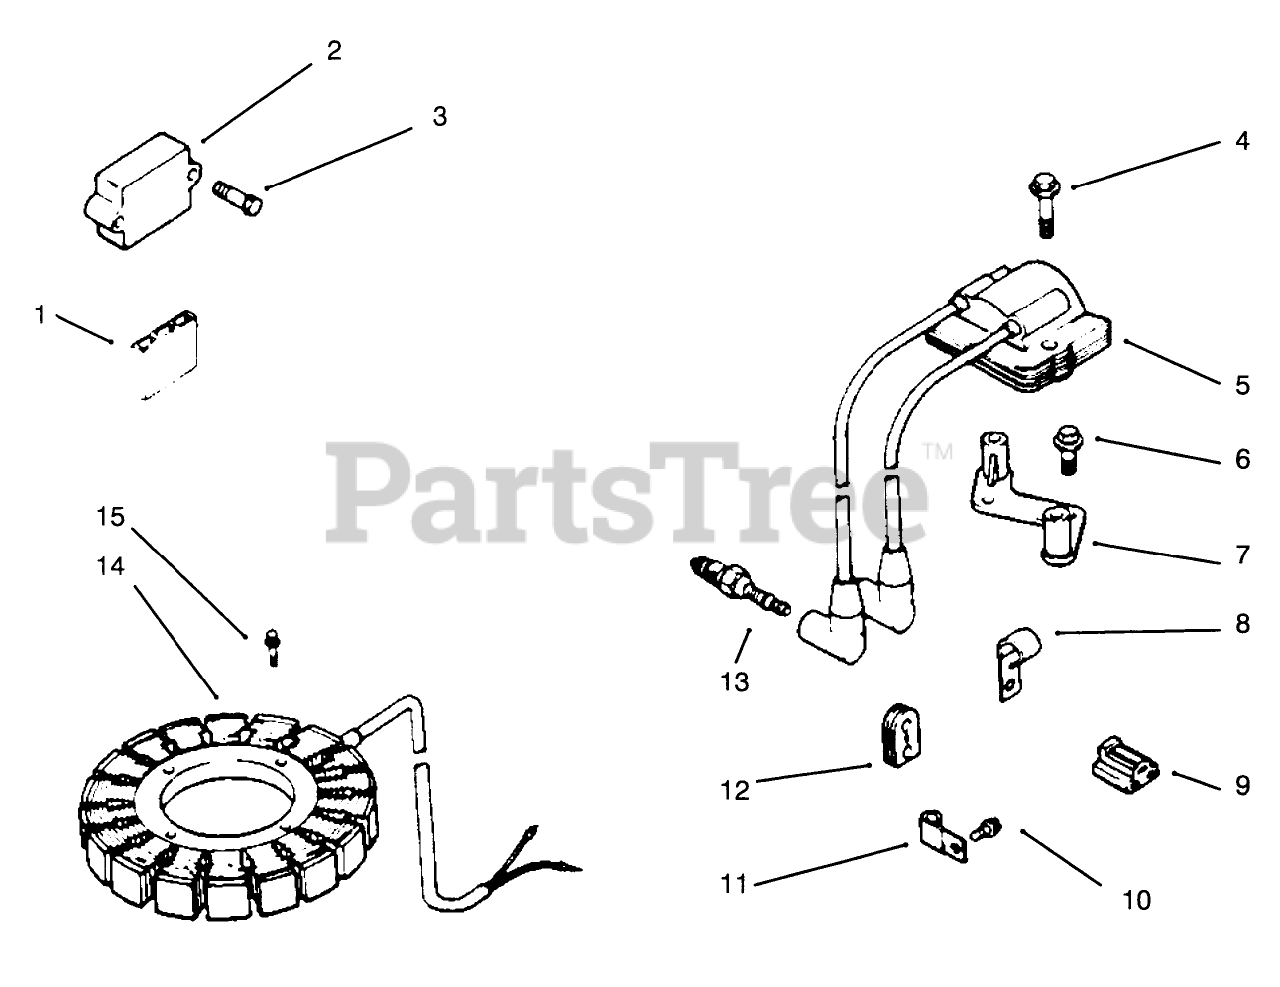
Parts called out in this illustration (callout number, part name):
1	Connector
2	Kit-Rectifier/Regulator (Incl. Ref. #2)
3	Screw
4	Screw-Hex Washer Hd.
5	Module-Ignition
6	Screw-Hex Washer Hd.
7	Bracket-Module
9	Connector
10	Screw
12	Grommet
13	Plug-Spark
14	Screw
15	Stator
